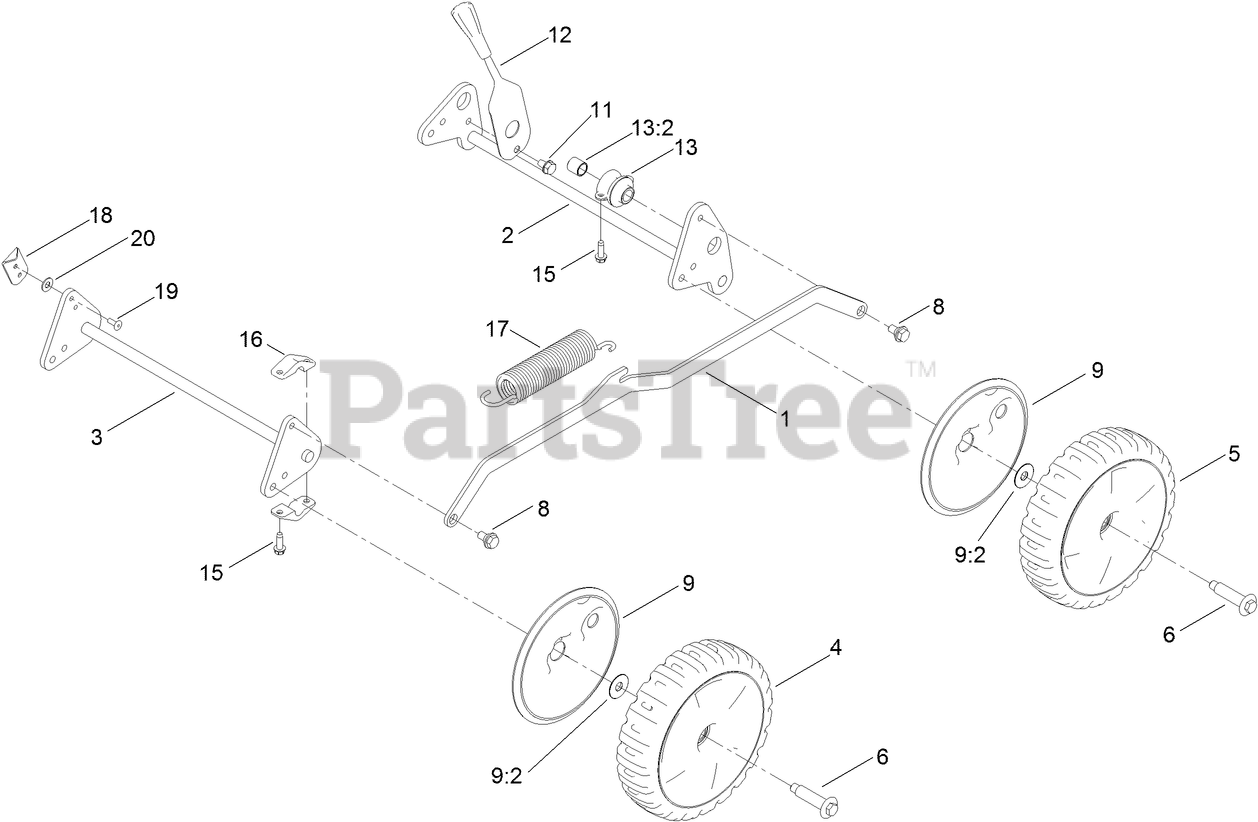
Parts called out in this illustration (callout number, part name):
1	BAR-CROSS, HOC
2	BAR-PIVOT, REAR
3	BAR-PIVOT, FRONT
4	8 INCH WHEEL ASM
5	8 INCH WHEEL AND GEAR ASM
6	BOLT-SHOULDER
8	SCREW-SHOULDER
9	WHEEL COVER ASM
9:2	WASHER-STEPPED
11	SCREW-THD CUT, HWH
12	HANDLE-LIFT ASSIST
13	BUSHING ASM
13:2	BUSHING
15	SCREW-HWHTF
16	MOUNT-AXLE, FRONT
17	SPRING-EXTENSION
18	INDICATOR-HOC
19	RIVET-BLIND
20	WASHER-FLAT
